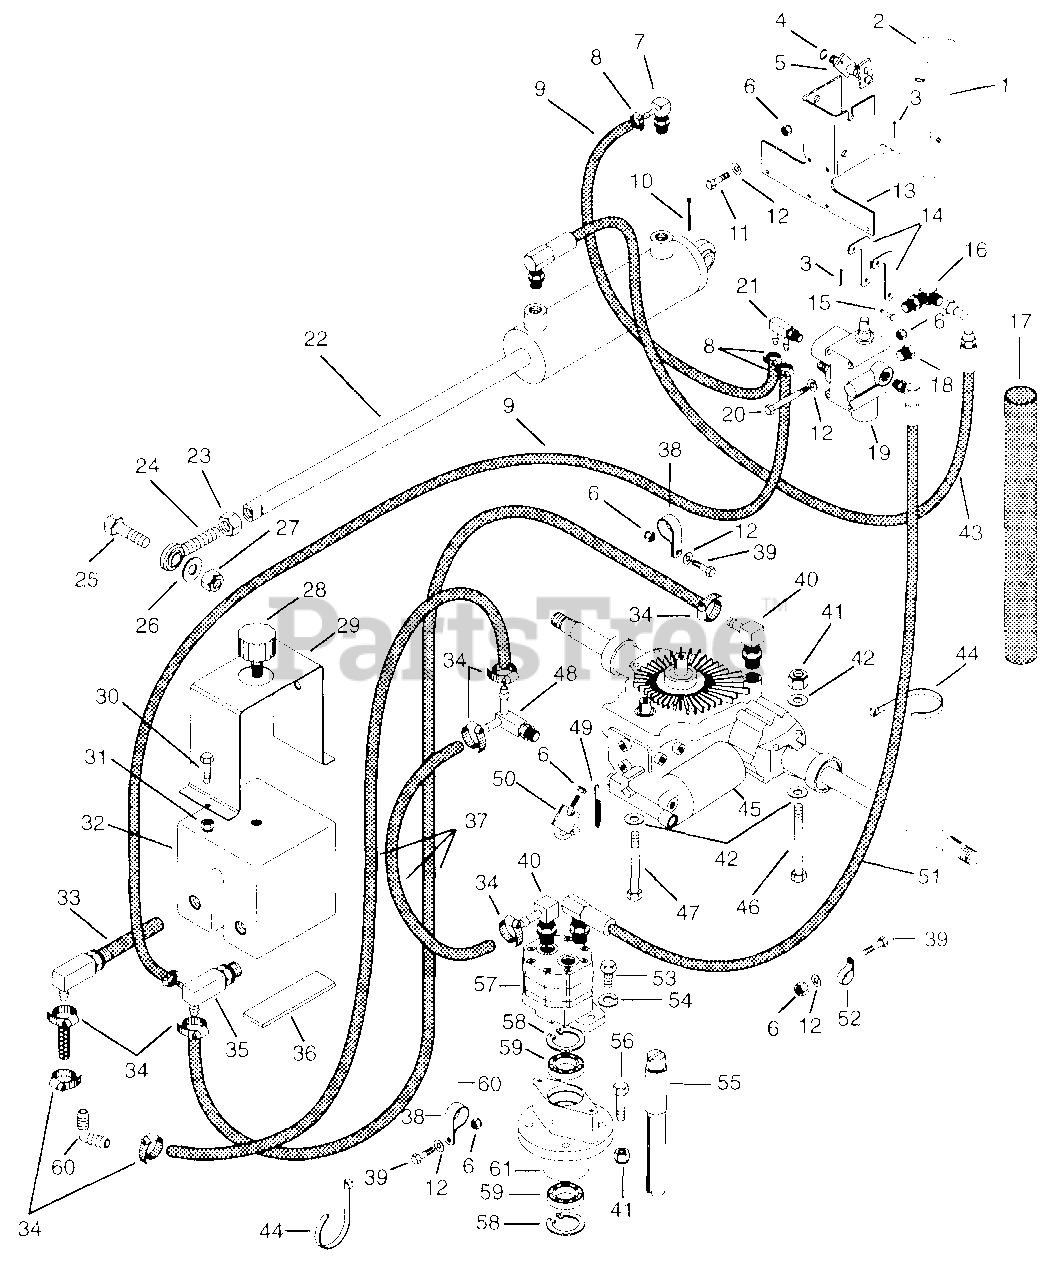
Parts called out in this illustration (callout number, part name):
1	Weldment, Lever
2	Grip, PTO Lever
3	Pin-Cotter .09 x .75
4	Ring-Retaining-External .392 x .042
5	Weldment, Linkage
6	Nut-Locking-Nylon .250-20
7	Fitting Adapter .562-18
8	Clamp-Hose .78 x .44 x 1.17
9	Hose, Hydraulic
10	Pin-Cotter .12 x 1.25
11	Bolt-Hex .25-20 x .75 Grade 5
12	Washer-Flat-Steel .281 x .620 x .065
13	Bracket
14	Lift Link
15	Pin-Clevis .189 x 1.0
16	Adapter 2503-6-4
17	Sleeve, Protective
18	Plug .44-20
19	Valve, Hydraulic
20	Bolt-Hex .25-20 x 3.00
21	Fitting-Pipe .563-18
22	Cylinder
23	Nut-Jam .50-20
24	Assembly, Rod End (Right Hand)
25	Bolt-Hex .50-13 x 1.75
26	Washer-Flat-Steel .531 x 1.062 x .095
27	Nut-Locking-Nylon .50-13
28	Cap, Filter
29	Strap, Tank
30	Bolt-Hex .31-18 x .75 Grade 5
31	Nut-Locking-Nylon .312-18
32	Tank Hydraulic
33	Fitting, Filter
34	Clamp, .88 Dia. Hose
35	Fitting with O-Ring 88-14 x .268
36	Pad, Gas Tank
37	Hose
38	Clamp, Steel 1.0
39	Bolt-Hex .25-20 x .875
40	Fitting
41	Nut-Locking-Nylon .375-16
42	Nut-Locking-Nylon .375-16
43	Assembly, Pressure Hose
44	Tie Wrap, Black
45	Filter, Oil
46	Bolt-Hex .38-16 x 4.00
47	Bolt-Hex .38-16 x 3.25 Grade 5
48	Fitting-Pipe .875-14
49	Spring-Tension .061 x .50 x 3.5
50	Weldment Lever
51	Assembly, Pressure Hose
52	Clamp, Cushioned Steel
53	Bolt-Hex .38-16 x .75 Grade 5
54	Washer-Lock .375 x .094
55	Shaft
56	Bolt-Hex .38-16 x 1.50 Grade 5
57	Pump, Hydraulic
58	ring-Retaining-Internal 2.210 x .062
59	Bearing-Ball 1.0 x 2.0 x .56
60	Elbow-Barbed .63 x .63
61	Housing
